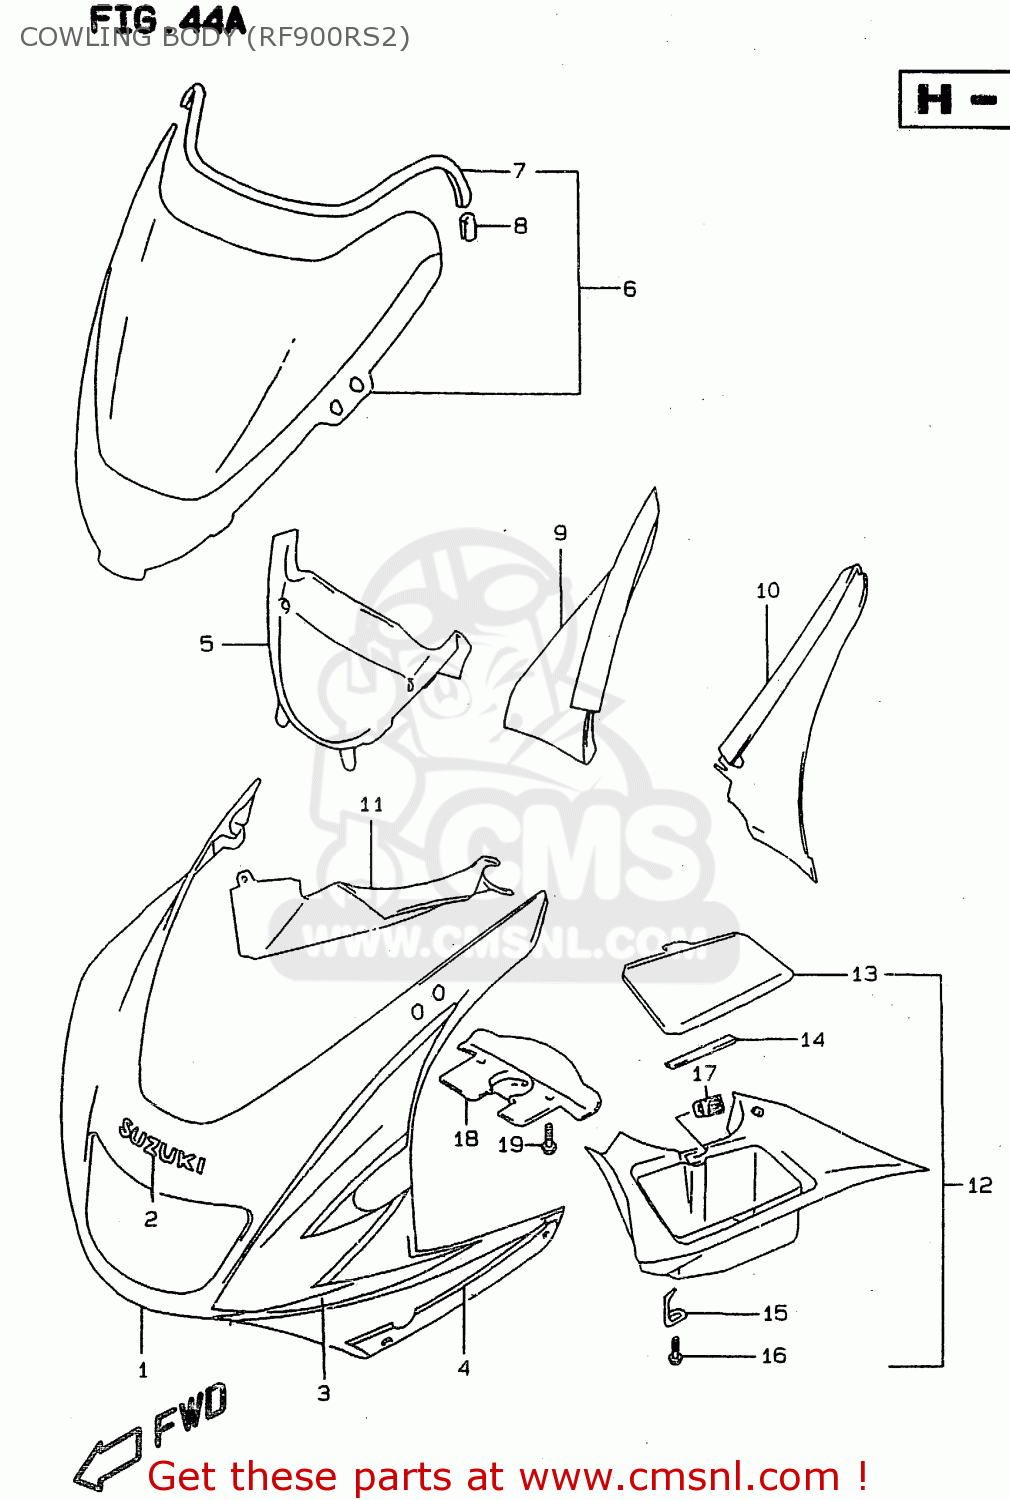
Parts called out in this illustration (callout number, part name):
1	COWLING ASSY,BODY(PURPLE)
2	EMBLEM,COWLING UPR
3	TAPE SET,COWL BODY FR
4	TAPE SET,COWL BODY SIDE
5	PANEL,COWLING CTR
6	WINDSCREEN SET
7	MOLDING WINDSCREEN
8	CLIP,WINDSCREEN MOLDING
9	PANEL,UPR,R
10	PANEL,UPR,L
11	PANEL,SIDE,R
12	PANEL ASSY,SIDE,L
13	LID,PANEL BOX
14	CUSHION,LID
15	HINGE,PANEL LID
16	SCREW
17	LOCK,I/P CTR BOX
18	COVER,COWLING FR LWR
19	BOLT(6X12)
